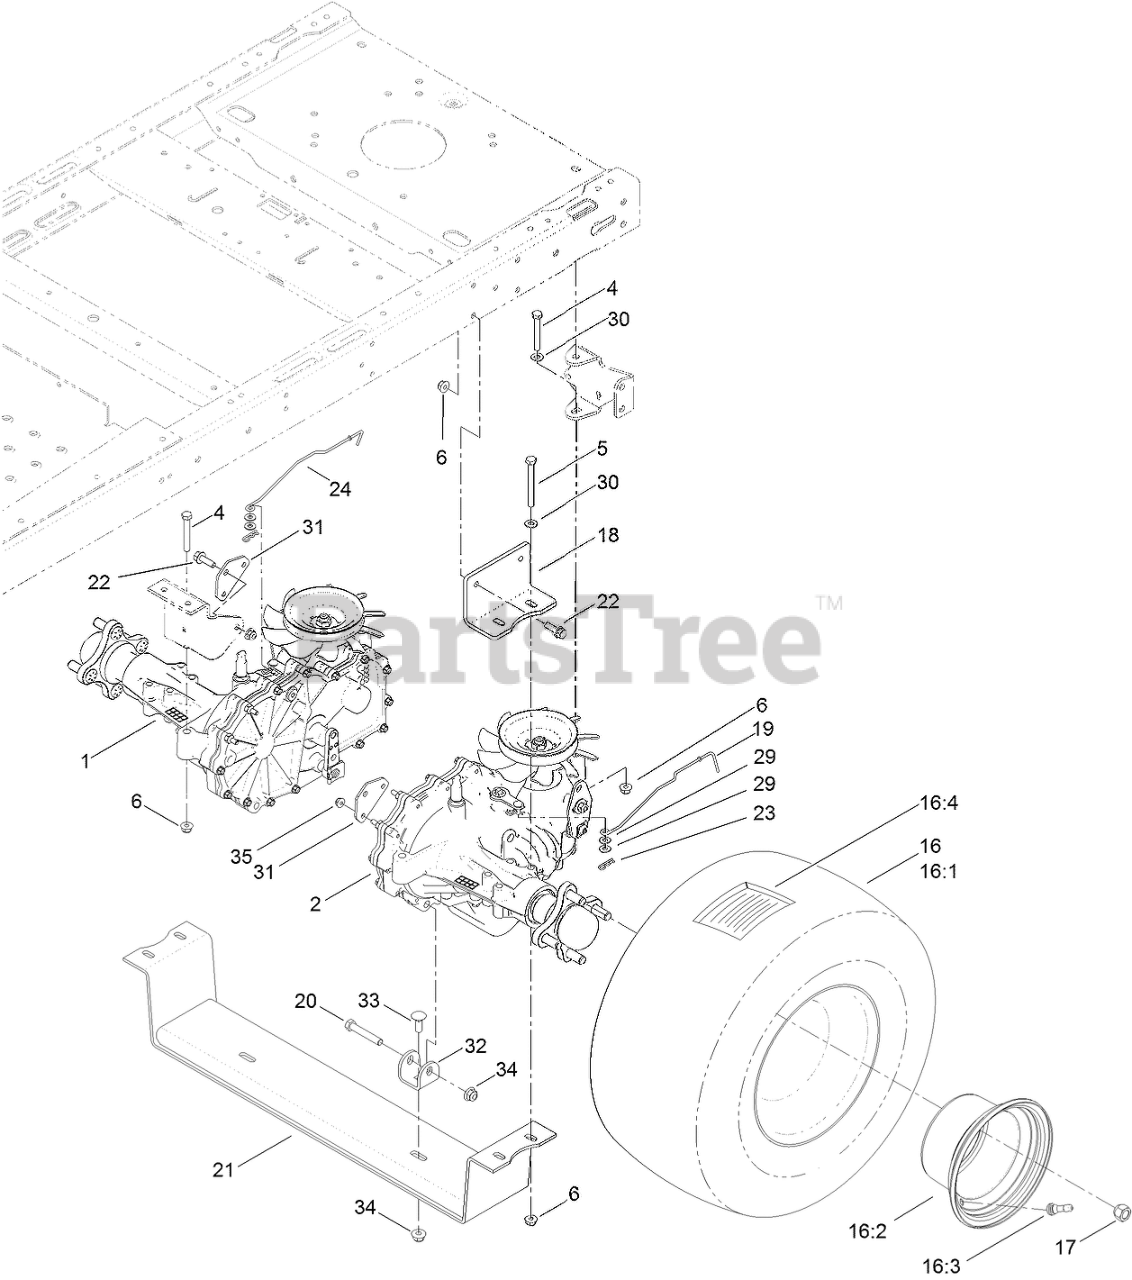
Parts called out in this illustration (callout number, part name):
1	RH HYDRO TRANSAXLE ASM
2	LH HYDRO TRANSAXLE ASM
4	SCREW-HH
5	SCREW-HH
6	NUT-HF, NI
16	4 PLY WHEEL AND TIRE ASM
16:2	TIRE-4 PLY
16:3	STEM-VALVE
16:4	TUBE-INNER
17	NUT-LUG
18	MOUNT-HYDRO
19	ROD-BYPASS, LH
20	SCREW-HH
21	MOUNT-HYDRO
22	SCREW-HHF
23	PIN-COTTER
24	ROD-BYPASS, RH
29	WASHER
30	WASHER-PLAIN
31	PLATE-HYDRO MOUNT
32	TAB-HYDRO
33	BOLT-CARR
34	NUT-HF, NI
35	NUT-HF
